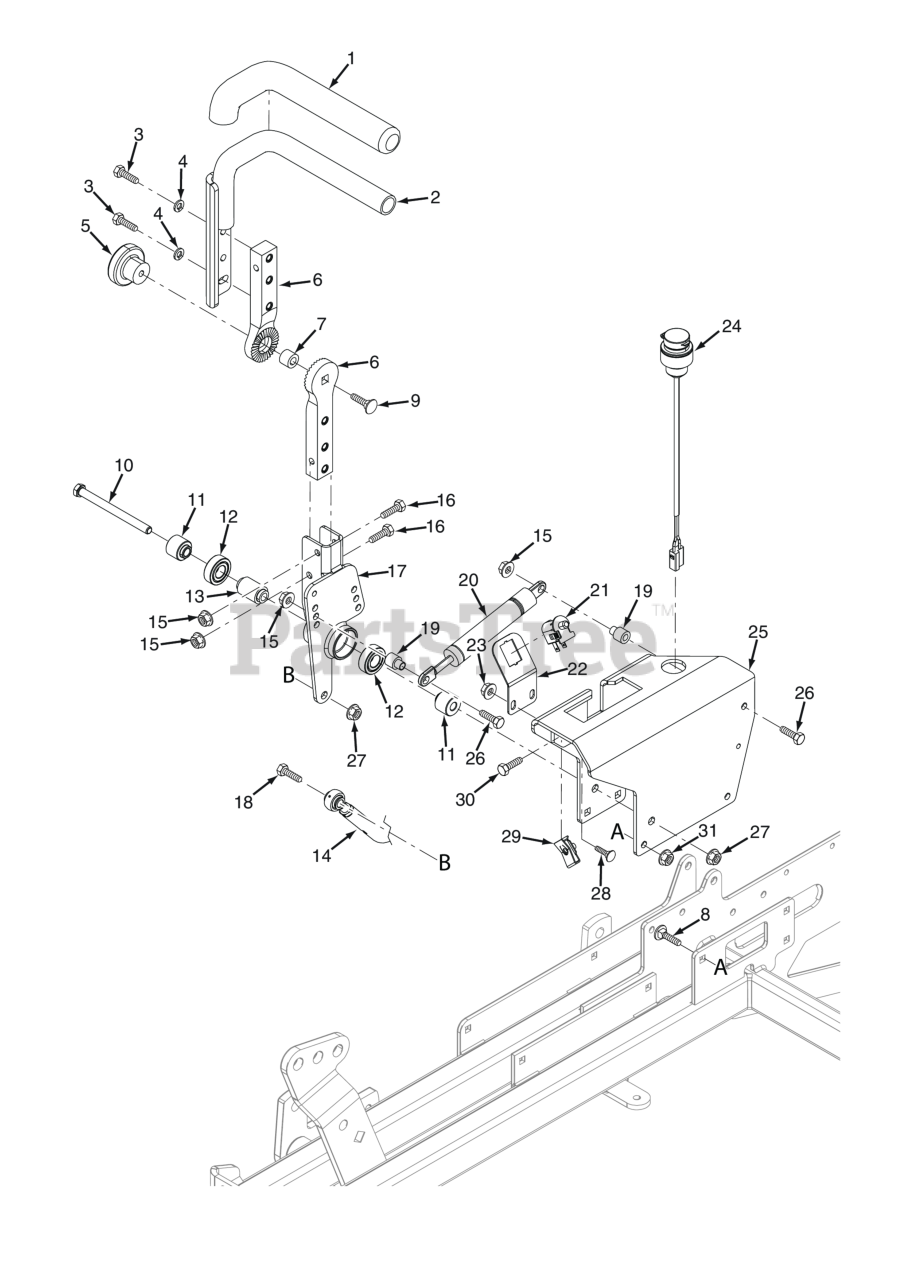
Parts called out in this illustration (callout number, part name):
1	Grip, Control Handle
2	Handle Bar w/Grip - RH
2	Handle Bar w/Grip - LH
3	Bolt, Heax Head 5/16-18 x 1" (48V / 52V)
4	Lockwasher, 5/16 (.317 x .586 x .078) Helical Spring
5	Knob, Control Handle
6	Pivot, Control Lever
7	Spacer, Rubber
8	Bolt, 5/16-18 x .75 RHSN Carriage
9	Bolt, RDHD Carr. 3/8-16 x 1-1/2 (52" & 61")
10	Bolt, 3/8 - 16 x 4 - 1/2" Hex Head
11	Spacer, Controls
12	BEARINGS, BALL, NEUTRAL RETURN
13	Spacer, Bearing
14	Nut, 3/8-24 UNF-2B LH Thread
14	Nut, 3/8-24 UNF R.H. Thread
15	HEX NUT, ELASTIC STOP LOCK, 5/16-18
16	Bolt, Hex Head 5/16-18 x 1-1/2" - Front
18	Bolt, Hex Head, 3/8-16 x 1-1/2"
19	Spacer, Pump Dampener
20	Damper, Steering
21	Switch, Interlock, Normally Open
22	Bracket, Operator Presence Switch
23	Nut, Flanged Elastic Stop 1/4-20
24	Power Plug, 12V
25	Control Weldment w/ Decal
26	Bolt, Hex Head 5/16-18 x 1-1/2" (Right Front Engine Mounting, Briggs and Kohler Only)
27	HEX NUT, ELASTIC STOP LOCK, 3/8-16
28	Serr. Fl. Hex Head CPSCR, 1/4-20 x 3/4"
29	U-Nut, 3/8-16 (short)
30	Bolt, Hex Head 3/8-16 x 1-1/4" with Thread Lock Patch
31	Nut, Serrated Flange 5/16-18 (Right Front Engine Mounting, Briggs and Kohler Only)
